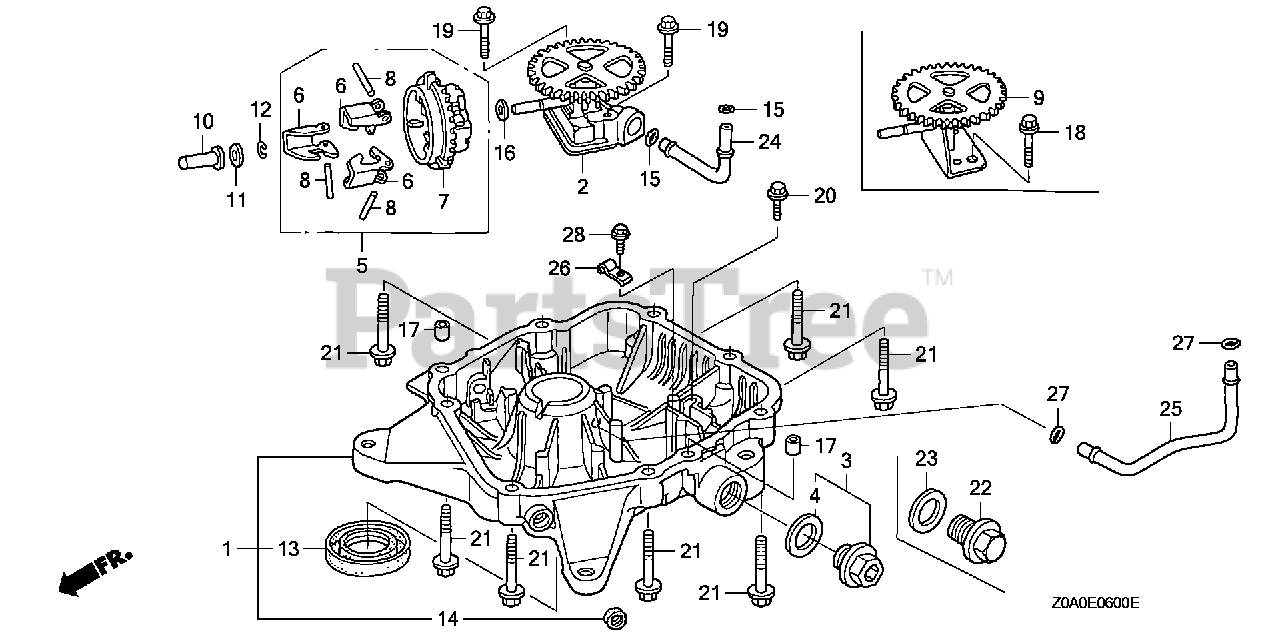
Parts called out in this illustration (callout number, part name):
1	PAN ASSY., OIL
5	GOVERNOR ASSY.
6	WEIGHT, GOVERNOR
7	HOLDER, GOVERNOR WEIGHT
8	PIN, GOVERNOR WEIGHT
9	SHAFT, GOVERNOR
10	SLIDER, GOVERNOR
11	WASHER (6X16)
12	CLIP, GOVERNOR HOLDER
13	OIL SEAL (31X50X8)
14	OIL SEAL (10X16X4.5)
16	WASHER, PLAIN (6MM)
17	PIN A, DOWEL (8X14)
18	BOLT, FLANGE (6X16) Use from Engine SN 2056820.
21	BOLT, FLANGE (8X40) Use up to Engine SN 1003236.
22	BOLT, DRAIN PLUG (20MM)
23	WASHER, DRAIN PLUG (20MM)
